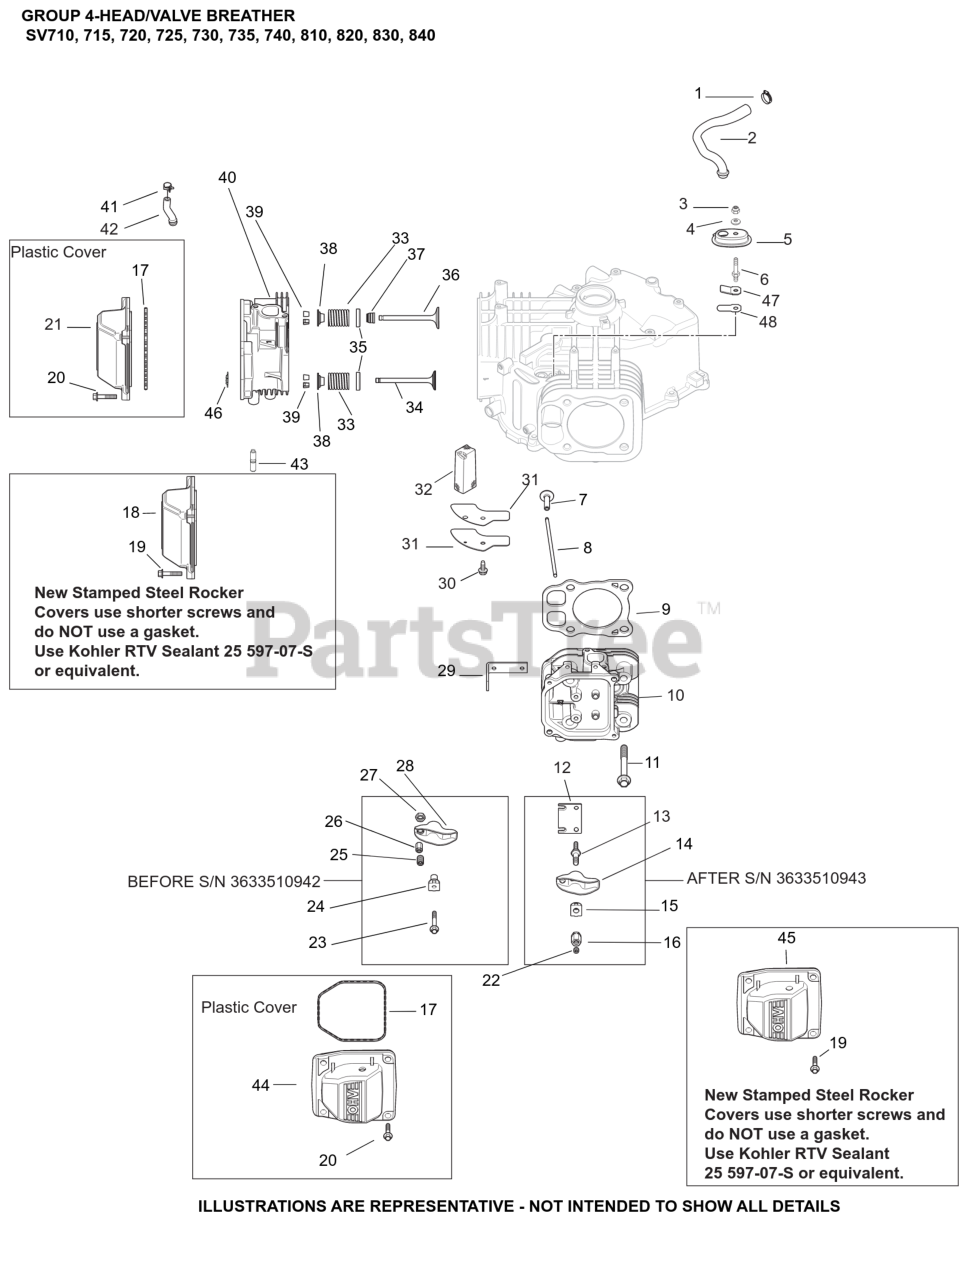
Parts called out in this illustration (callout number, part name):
1	CLAMP, HOSE (KM)-USE 25 237 31-S
2	KIT, BREATHER HOSE
3	NUT, LOCK M5X.8
4	WASHER, SEALING
5	KIT, BREATHER HOUSING
6	STUD, BREATHER COVER
8	ROD, PUSH
9	KIT, CYLINDER HEAD GASKET
10	KIT, CYL HEAD ASSY (#2)-(#3231822S)
11	SCREW, FLG M10X1.5X90
12	PLATE, GUIDE
13	STUD, ROCKER
14	ARM, ROCKER
15	PIVOT, ROCKER ARM
16	HEX NUT ASSEMBLY
17	O-RING (YELLOW), VALVE CO
18	COVER, ROCKER STAMPED STEEL
19	SCREW, PAN HEAD-(#25086660S)
20	SCREW, FLG M6X1.0X30
21	KIT, VALVE COVER-PLAIN (PLASTIC)
22	SCREW, SET
23	SCREW, FLG M6X1.0X45-USE 25 086 764-S
24	PIVOT, ROCKER ARM
25	SCREW, SET
26	NUT, HEX
27	NUT, M10X0.75
28	KIT, ROCKER ARM
29	STRAP, LIFT
30	SCREW, THREAD FORMING
31	GASKET, BREATHER COVER - DISC.
31	COVER, BREATHER
32	FILTER, BREATHER
33	SPRING, VALVE-USE 25 089 17-S
34	VALVE, EXHAUST
34	VALVE, EXHAUST (.25)
36	VALVE, INTAKE
36	VALVE, INTAKE (.25) - (#2401702S)
37	SEAL, VALVE BAND
38	CAP, VALVE SPRING
39	KIT, RETAINER
40	HEAD ASSY,CYLINDER (#1)-(#3231821S)
44	KIT,BREATHER VALVE COVER (PLASTIC)
45	COVER, ROCKER (STEEL)- (#3275542S)
46	RETAINER, VALVE GUIDE (KM)
47	RETAINER, BREATHER REED
48	REED, BREATHER
